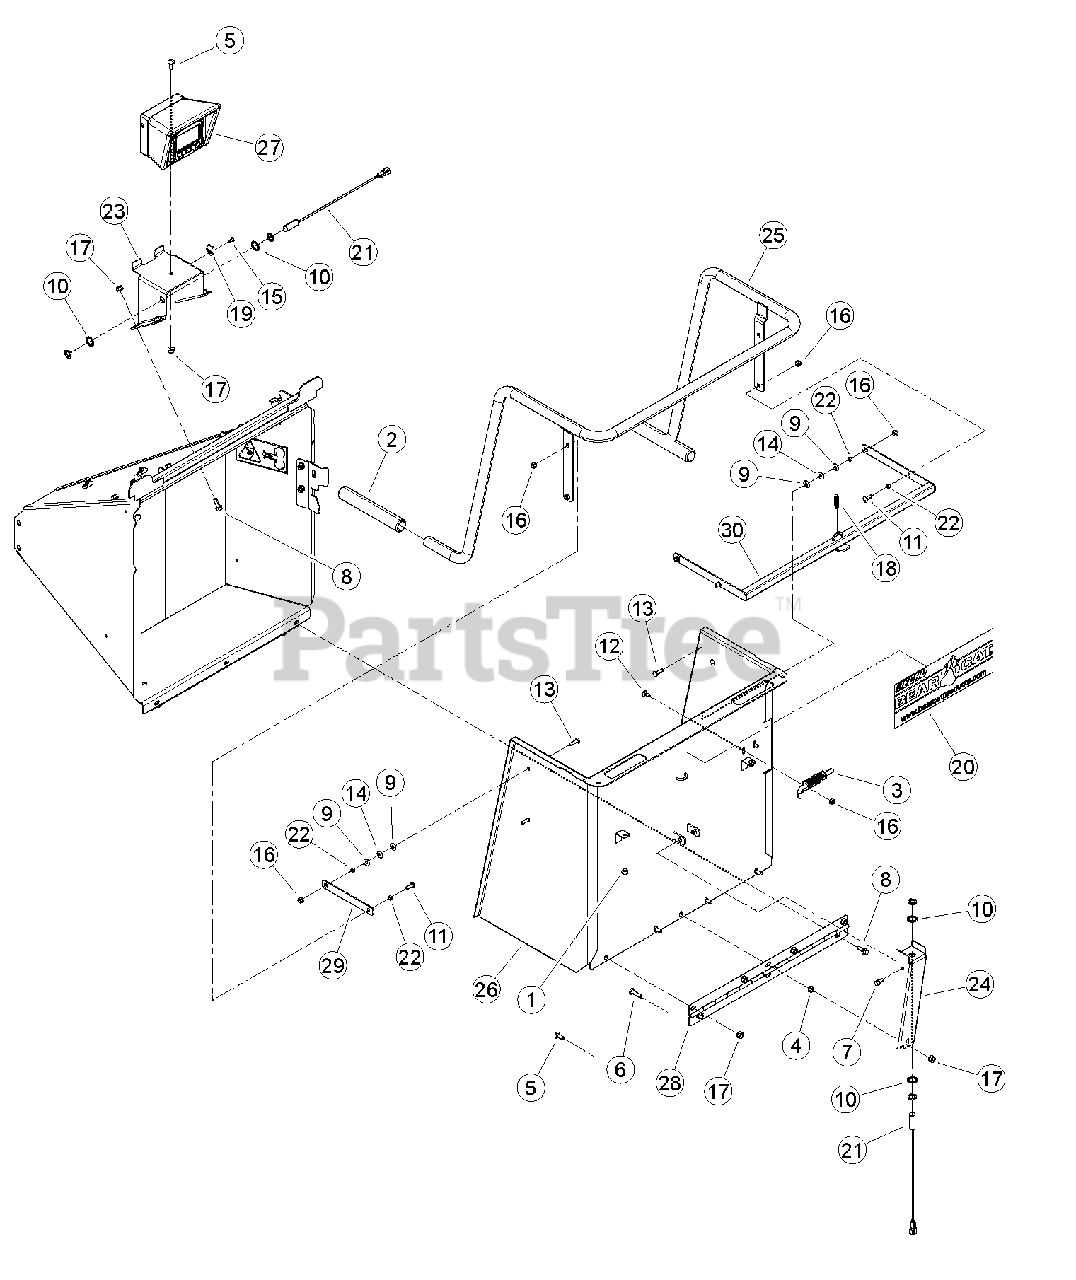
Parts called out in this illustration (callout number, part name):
1	BUMPER, RUBBER
2	GRIP, 1.219 X 10.00
3	LATCH, RH HINGE
4	NUT, 3/8-16 SERRATED FLANGE
5	BOLT, 3/8-16 X 1 GR5 CRG
6	BOLT, 3/8-16 X 1-1/2 GR5 CRG
7	BOLT, 5/16 X 3/4 FLANGE NC
8	BOLT, 3/8 X 1 FLANGE NC
9	WASHER, 5/16 FLAT
10	WASHER, 3/4 INTERNAL LOCK
11	BOLT, 5/16-18 X 1 GR5 CRG
12	BOLT, 5/16 X 3/4 GR5 CRG NC ZP
13	BOLT, 5/16 X 1-1/4 GR5 CRG
14	WASHER, 5/16" ID 7/8" OD NYLON FLAT
15	RIVET, AL BLIND 1/4 X 3/4 DOME HEAD
16	NUT, 5/16-18 NYLOCK FLANGE
17	NUT, 3/8-16 NYLOCK FLANGE
18	SPRING, 1/2 X 2.00 LG
19	CLAMP, CABLE MOUNT
20	DECAL, BEARCAT WEB
21	SENSOR, M18 PROXIMITY (REPLACEMENT PART)
22	SPACER, IDLER PIVOT
23	MOUNT, 5"/8"/9" DDC
24	MOUNT, 5"/8"/9" KNEEBAR PROX SENSOR
25	WELDMENT, 5" SAFETY KNEEBAR
26	WELDMENT, INFEED TRAY 5"
27	ASSEMBLY, DDC ENCLOSURE
28	HINGE, EXTENSION TRAY
29	LINK, PARALLEL
30	WELDMENT, PIVOT TUBE
